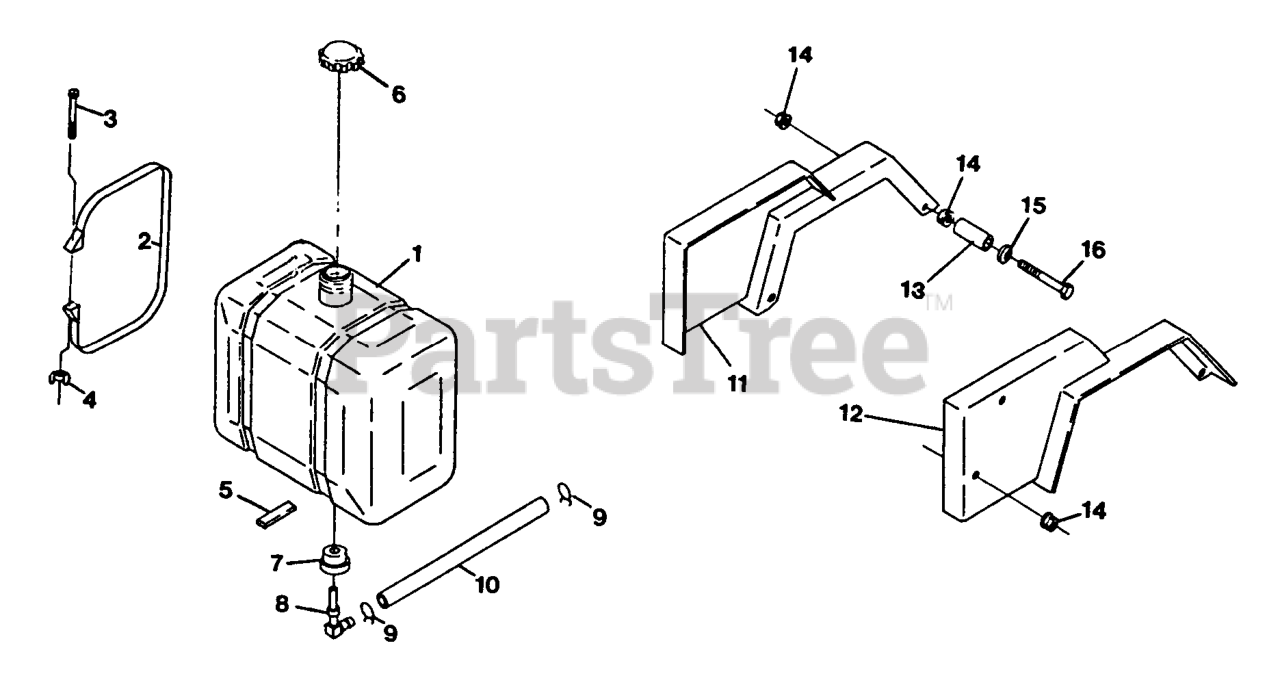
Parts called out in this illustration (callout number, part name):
3	SCRW,MACH CRPH
4	WINGNUT
5	PAD,PLASTIC TANK
6	CAP-FUEL
9	CLAMP
13	SPACER-FENDER
